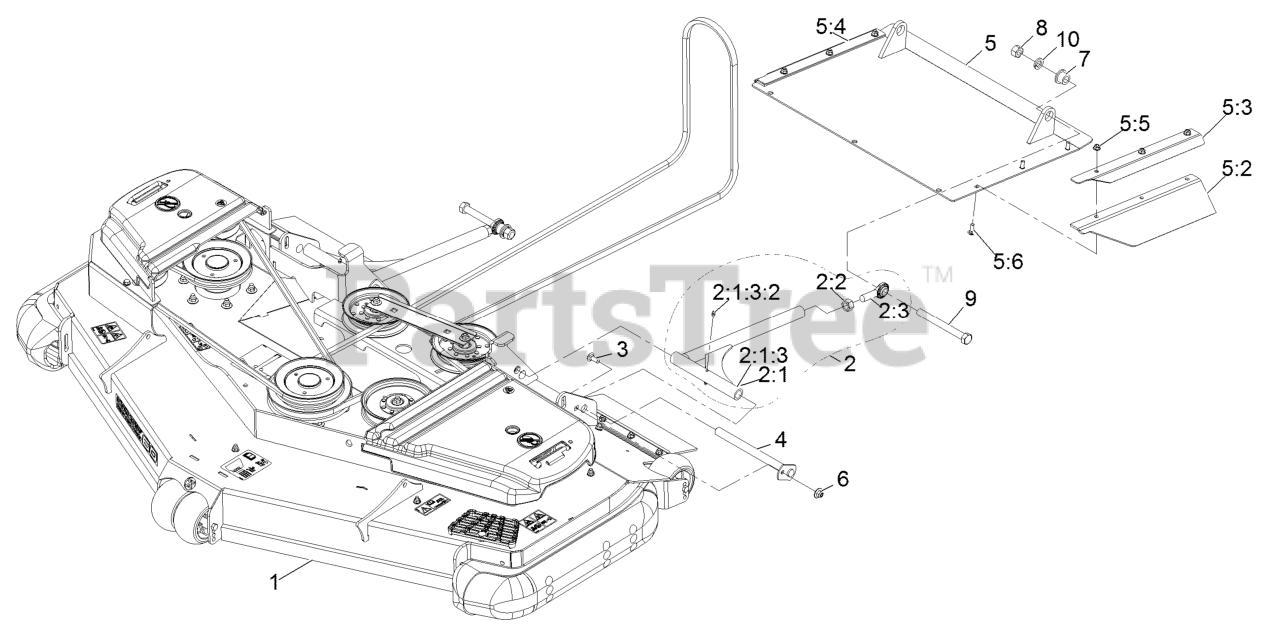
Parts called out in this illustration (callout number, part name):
1	ASM-Deck Complete Rd60
2	ASM,DECK STRUT XS 60
2:1	STRUT-DECK
2:1:3	Tube And Zerk ASM
2:2	NUT-HEX
2:3	BALLJOINT-SPHERICAL
3	BOLT-CARR
4	PIN-STRUT
5	ASM-DISCHARGE TUNNEL RD60
5:2	FLAP-RD TUNNEL SIDE
5:3	BRKT-RD TUNNEL FLAP LH
5:4	BRKT-RD TUNNEL FLAP RH
5:5	NUT-HF, NI
5:6	SCREW-CARR
6	Nut-Nyloc 3/8-16 Flg
7	BUSHING-FLANGE
8	NUT-HEX
10	WASHER-LOCK
